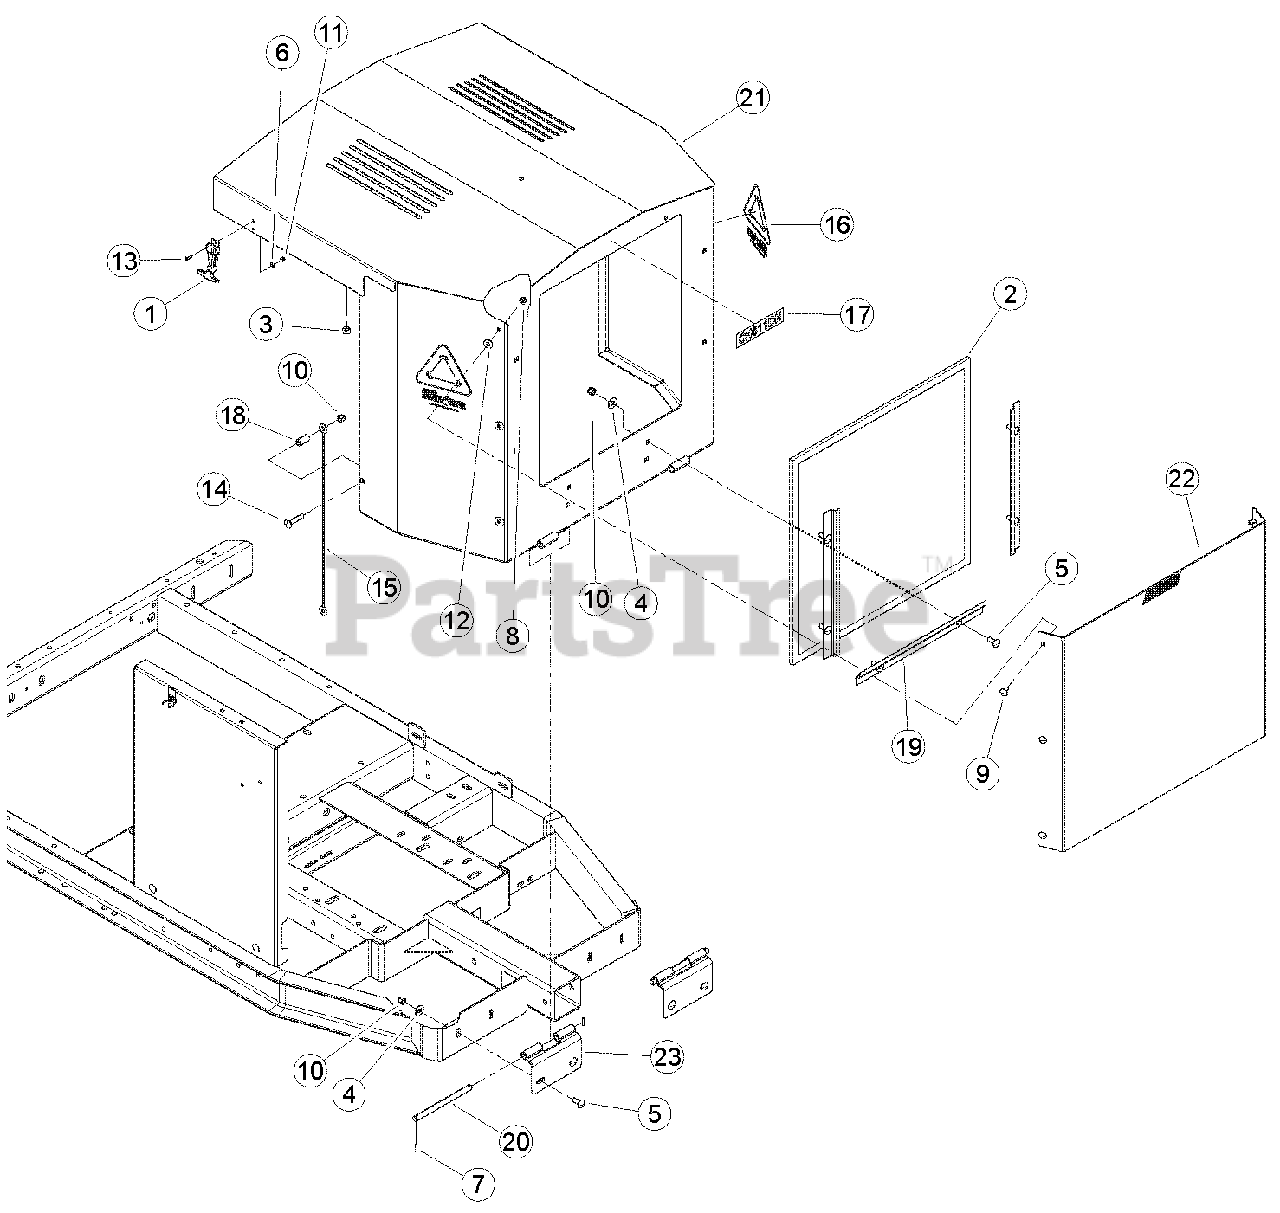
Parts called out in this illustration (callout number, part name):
1	LATCH, FLEXIBLE DRAW
2	SCREEN, RADIATOR INLET
3	BUMPER, RUBBER
4	WASHER, 3/8 FLAT ZP
5	BOLT, 3/8 X 1 CRG GR5 NC ZP
6	WASHER, 3/16 FLAT ZP
7	ROLL PIN, 5/32 X 3/4" PLAIN
8	NUT, 5/16 NE NYLOCK ZP
9	BOLT, 5/16 X 3/4 CRG GR5 NC ZP
10	NUT, 3/8 NE NYLOCK ZP
11	NUT, 10/24 NYLOCK TYPE NM, ZP
12	WASHER, 5/16"ID 7/8"OD NYLON FLAT
13	SCREW, 10-24 X 1/2 MCH PAN HD,PH ZP
14	BOLT, SHOULDER 1.88" LONG CRG GR5 ZP
15	LANYARD, STEEL W/PVC 1/8" X 20"
16	DECAL, CHIP IT
17	DECAL, MODEL CH611DH
18	IDLER SPACER
19	BRACKET, SCREEN HOLDER
20	PIN, HOOD HINGE PLATED
21	WELDMENT, 6 INCH HOOD
22	GUARD, 6" CHIPPER ROCK
23	WELDMENT, HOOD HINGE
